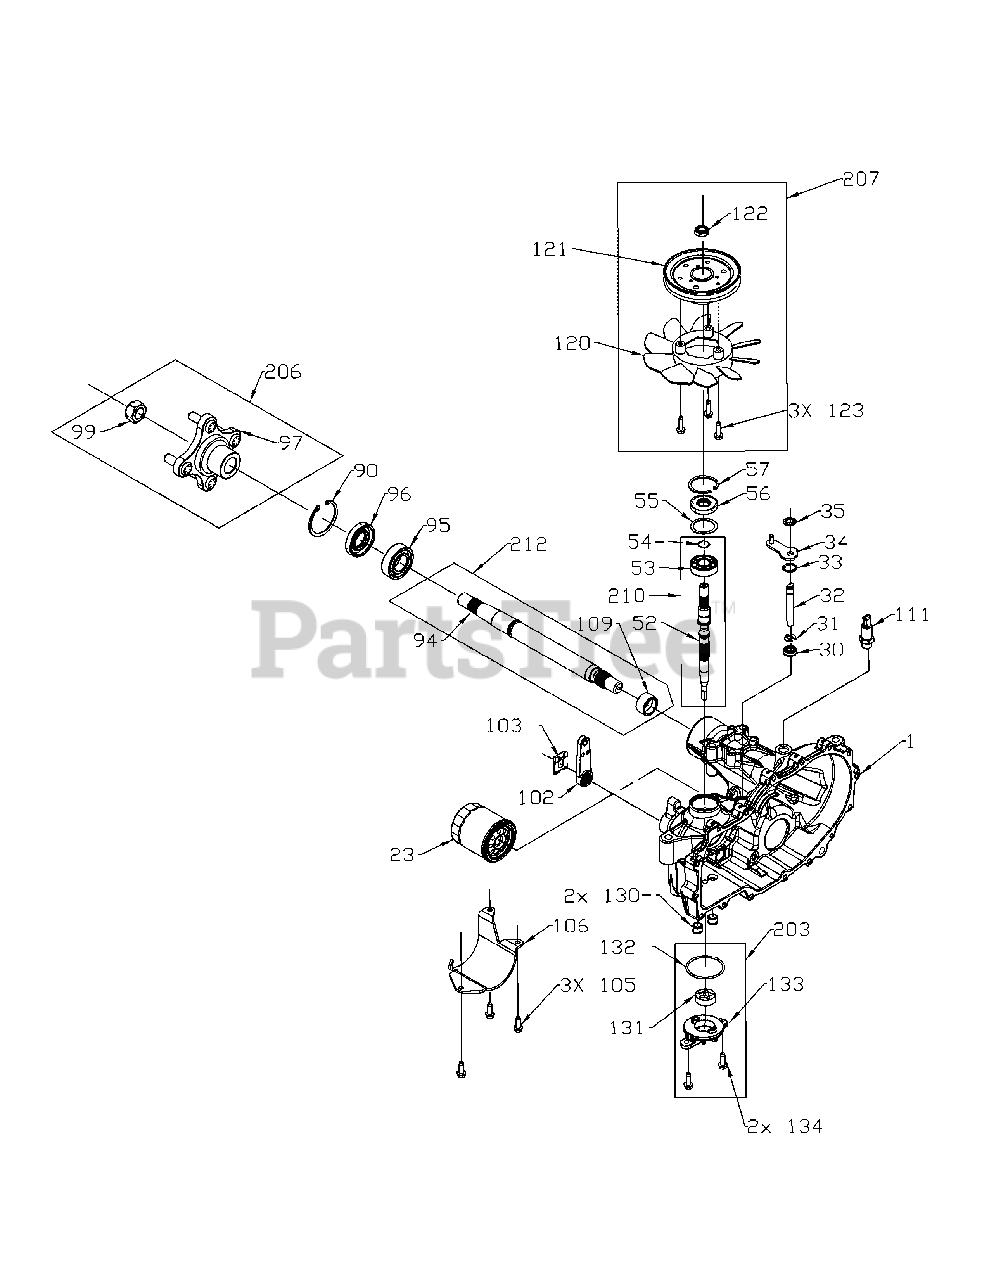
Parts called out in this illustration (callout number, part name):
1	Kit, Housing Main RH Chrg
1	Housing, Main RH Chrg
1	Bushing .624 x .719 x .562
1	Brg, Jrnl .86 x .98 x .79
1	Pin .25 x .375
2	Kit, Cover Side RH Cntl
2	Cover, Side RH Cntl
2	Bushing .624 x .719 x .562
2	Brg, Jrnl .86 x .98 x .79
7	HFHCS 1/4-20 x 1.25''
10	O-Ring 111.103 x .424
11	Plug 9/16/18 (Metal)
20	Center Section, RH Chrg
22	Plate, Bypass
23	Filter, Oil
24	Shock Valve
25	Shock Valve
26	Seal, Plug 1.250 x .250
27	HFHCS 3/8-16 x 1.5 (Patch)
30	Seal, Lip .375 x .75 x .25
31	Ring, Ret .375 External
32	Rod, Bypass
33	Ring, Ret .750 Internal
34	Arm, Bypass
35	Ring, Rtng .375 Ext
40	Trunnion, Swashplate
41	Seal, Lip 18 x 32 x 7
44	Arm, Control
45	Washer .34 x .88 x .06
46	TWHCS 5/16-24 x 1.00 (Patch)
52	Shaft, Input
53	Brg, Ball 17 x 40 x 12 Open 6203
54	Ring, Ret Wire .561 ID
55	Washer 1.23 x 1.56 x .04
56	Seal, Lip 17 x 40 x 7
57	Ring, Ret 2.06 Internal
60	Bearing, Thrust
64	Cylinder Block Assembly 16cc
65	Bearing, Thrust Ball 30 x 52 x 13
69	Block 7 Piston Assembly
70	Washer .63 x 1.0 x .05
71	Ring, Ret 62 External
72	Gear, 16T
73	Shaft, Motor
74	Washer .72 x 1.16 x .04
80	Washer .5 x 1.0 x .03
81	Gear, 43T
82	Gear, 11T
83	Jack Shaft (Pin)
90	Ring, Ret 2.06 Internal
91	Gear, 54T
92	Spacer, .750 x 1.000 x .257
93	Bearing Ball .75 x 40 x 12
94	Shaft, Axle
95	Bearing Ball 1.0 x 52 x 15 Open 6205M
96	Seal, Lip TC4 (Gray)
97	Hub, 4 Stud (3.56 Taper)
99	Nut, Hex Lock 3/4-16
100	Pawl, Brake
101	Shaft, Brake
102	Handle, Brake
103	Clip, Retaining
105	HFHCS 1/4-20 x .75
106	Guard, Filter - RH
109	Spacer, .91 x 1.02 x .625
111	Fitting, Str 9/16-18 SAE .5 Barb
120	Fan, 7'', 10 Blade
121	Pulley 4.5 Inch
122	Nut, Hex Lock 1/2-20 Nylon
123	HFHCS 1/4-20 x .75
130	Tube, Connecting
131	Gerotor Assembly (1.6 cc/rev)
132	O-Ring, -137, 0.103 x 2.050
133	Cover, Charge Pump
134	HFHCS 1/4-20 x .75
135	Ball, Steel 7/16''
136	Spring relief .42 x .250
137	Pin, Spring .125 x .875
140	Spacer, .320 x 1.005 x .179
141	Arm, Neutral Right
142	SHCS 5/16-24 x 1 (Patch)
145	Assembly, RTN
146	Washer, .343 x 1.500 x .062
147	Spring, Extension .57 x 2''
148	Bracket Damper
200	Kit, Seal
201	Kit, Center Section, RH Chrg
202	Kit, Chrg Relief
203	Kit, Charge
206	Kit, Hub 4 Bolt
207	Kit, Fan/ Pulley
209	Hub Puller, 4 Bolt
210	Kit, Input Shaft
211	Kit, RTN Bidirectional RH
212	Kit, Axle Shaft
